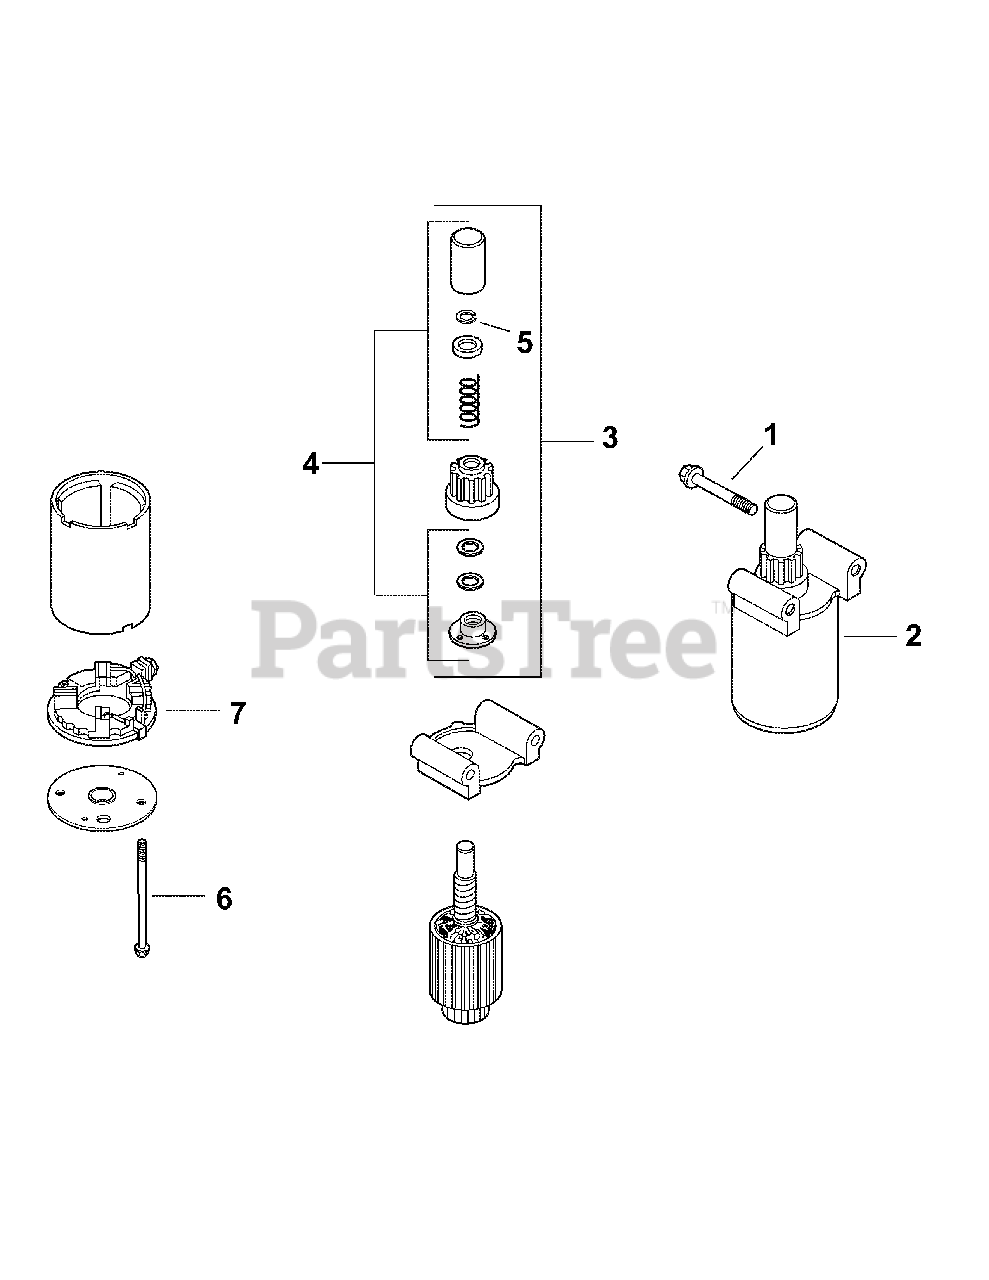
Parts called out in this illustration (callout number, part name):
1	Screw, FLG M8 x 1.25 x 80
2	Starter Assembly
4	Kit, Drive Parts (Includes 5)
5	Ring, Retaining
7	Commutator, End Cap
